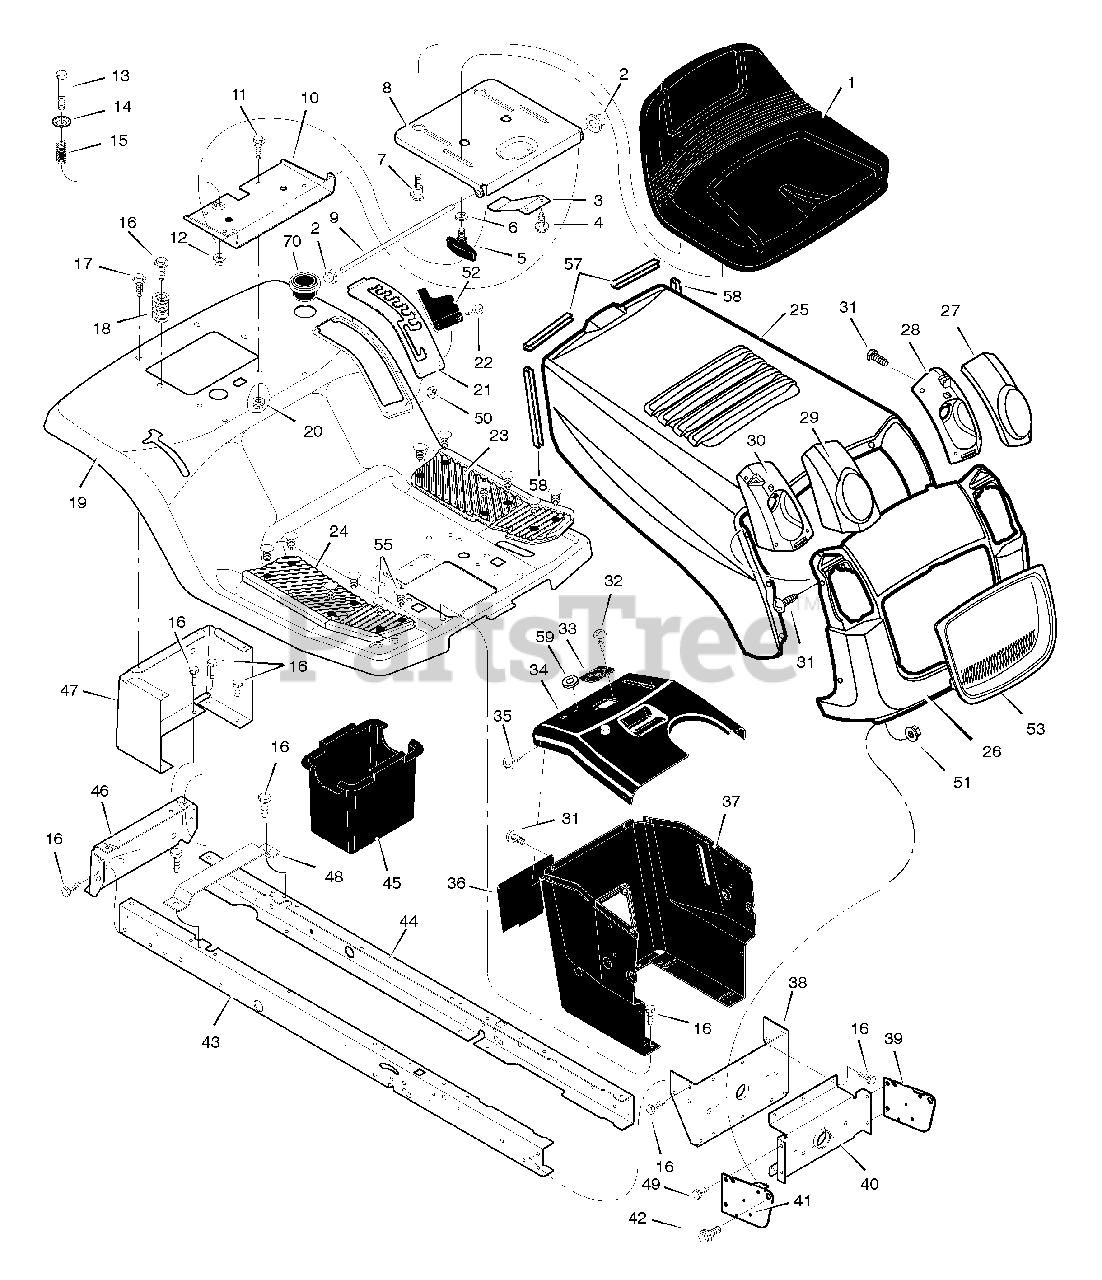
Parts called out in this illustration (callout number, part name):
1	Seat
2	Cap, Push 0n
5	Bolt, Wing
6	Washer
7	Bolt, Shoulder
8	Support, Seat
9	Rod, Pivot
10	Bracket, Pivot
11	Bolt
13	Bolt, Shoulder
15	Spring
19	Deck, Seat
20	Nut
21	Plate, Index
23	Mat, Left
24	Mat, Right
25	Hood
26	Grille
27	Lens, Left
28	Housing, Left Headlamp
29	Lens, Right
30	Housing, Right Headlamp
31	Screw
33	Bearing, Steering
34	Dash
36	Panel, Access
37	Support, Dash
38	Bracket, Rear Hanger
39	Support, Left Grille
40	Axle, Hanger
41	Support, Right Grille
42	Bolt, Shoulder
43	Frame, Right
44	Frame, Left
45	Container, Battery
46	Plate, Hitch
47	Panel, Rear
48	Support, Battery
52	Cover, Lift Detent
53	Insert, Grille
55	Fastener, Panel
57	Trim, Hood (3.75")
58	Trim, Hood (6.5")
59	Grommet, Parking Brake
70	Holder, Cup
